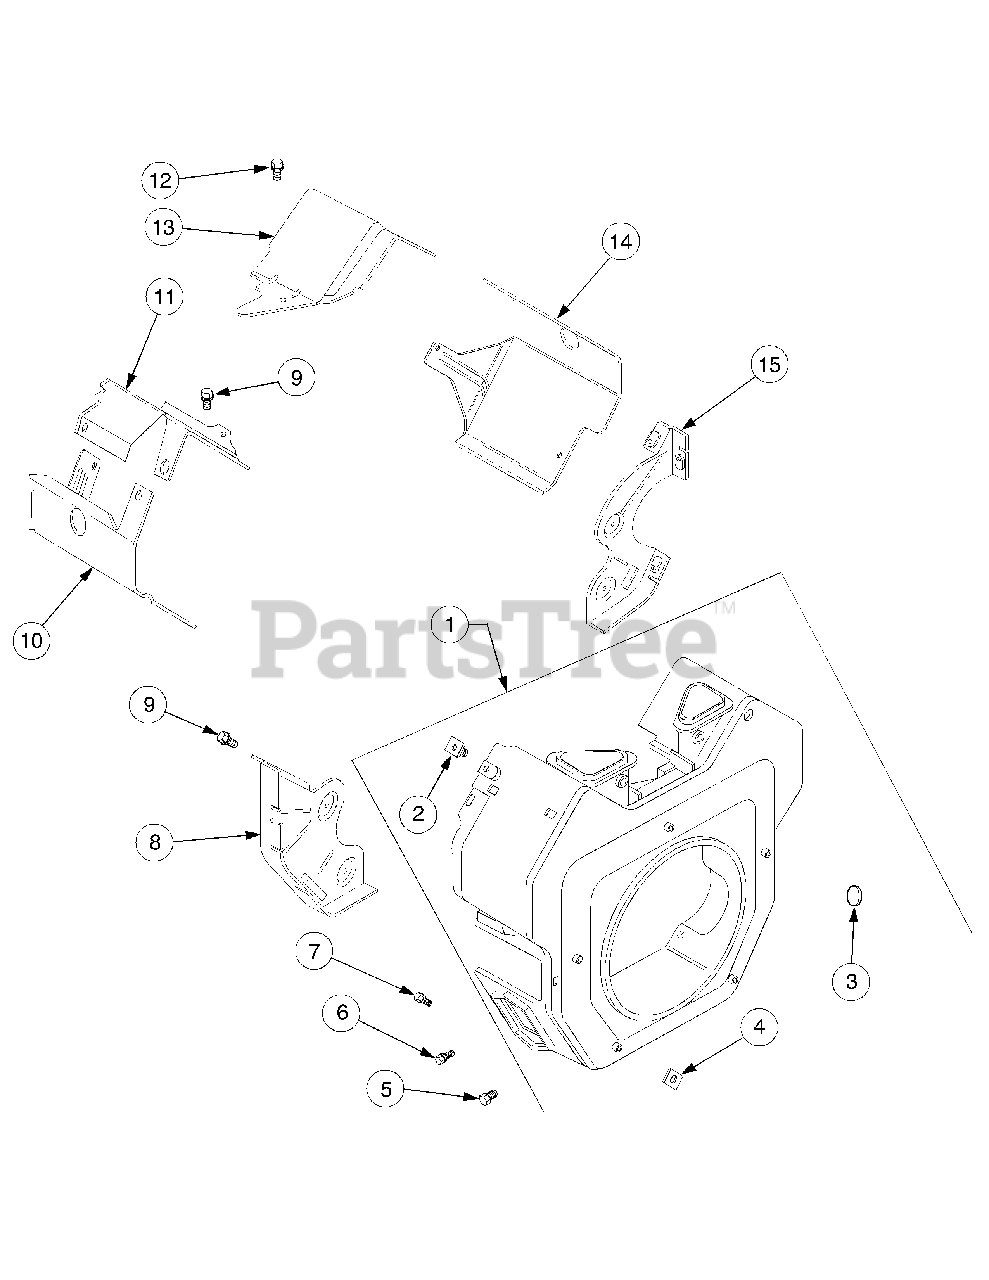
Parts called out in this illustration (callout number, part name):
1	Housing, Blower (Incl. Ref #2-4)
2	Nut, Plastic
3	Plug, Button, 9/16
4	Nut, Plastic
5	Screw, Hex Flange, M5 x 0.8 x 16
6	Screw, Hex Flange, M5 x 0.8 x 16
7	Screw, Hex Flange, M5 x 0.8 x 20
8	Plate, Backing - #2 Side
9	Screw, Hex Flange, M6 x 1.0 x 16
10	Baffle, Cylinder Barrel - #2 Side
11	Baffle, Valley - #2 Side
12	Screw, Hex Flange, M5 x 0.8 x 10
13	Baffle, Valley - #1 Side
14	Baffle, Cylinder Barrel - #1 Side
15	Plate, Backing - #1 Side
